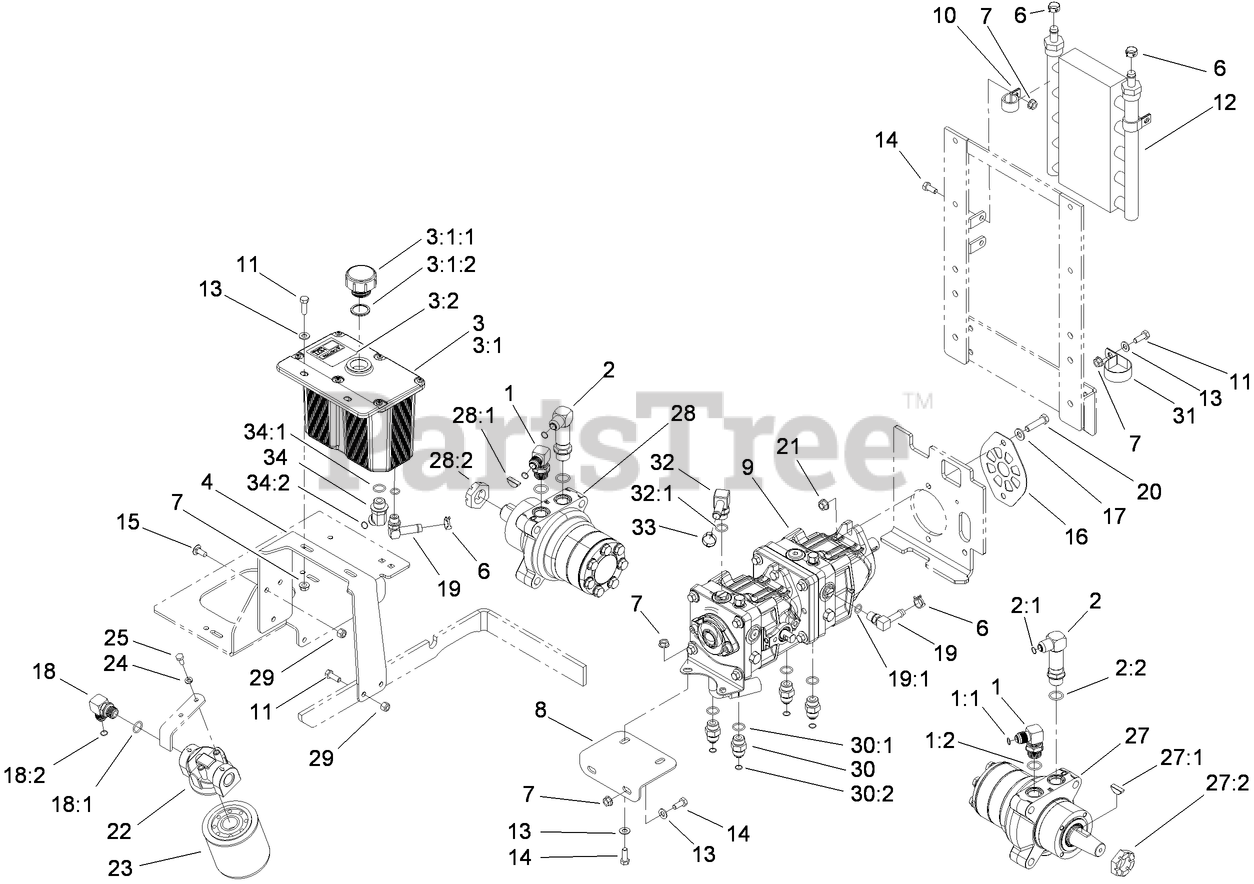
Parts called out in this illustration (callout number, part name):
1	FITTING-HYD, 90 DEG
1:1	O-Ring
1:2	O-RING
2	FITTING-ELBOW-90
2:1	O-Ring
2:2	O-RING
3	HYDRAULIC TANK ASM
3:1	TANK-HYDRAULIC
3:1:1	CAP-RESERVOIR, HYD
3:1:2	GASKET-CAP
3:2	DECAL-TANK, HYD
4	BRACKET-TANK, HYDRAULIC
6	CLAMP-HOSE
7	NUT-HF
8	BRACKET-PUMP, FRONT
9	TANDEM PUMP ASM
10	R-CLAMP
11	SCREW-HH
12	COOLER-OIL, HYDRO
13	WASHER-PLAIN
14	SCREW-HH
15	SCREW-CARR
16	PLATE-SHIELD, PUMP
17	WASHER-FLAT
18	FITTING-90 DEG
18:1	O-RING
18:2	O-Ring
19	FITTING-ELBOW, 90
19:1	O-Ring
20	SCREW-HH
21	NUT-HHF, WHIZ
22	HEAD-FILTER
23	CARTRIDGE-FILTER, OIL
24	WASHER-LOCK
25	SCREW-HH
27	HYD MOTOR ASM (CCW)
27:1	KEY-WOODRUFF
27:2	NUT-HH
28	HYD MOTOR ASM (CW)
28:1	KEY-WOODRUFF
28:2	NUT-HH
29	NUT-LOCK, NI
30	FITTING-STRAIGHT
30:1	O-RING
30:2	O-Ring
31	CLAMP-R
32	FITTING-ELBOW, 90 DEG
32:1	O-RING
33	CLAMP-HOSE
34	FITTING-HYD, 45 DEG
34:1	O-RING
34:2	O-Ring
